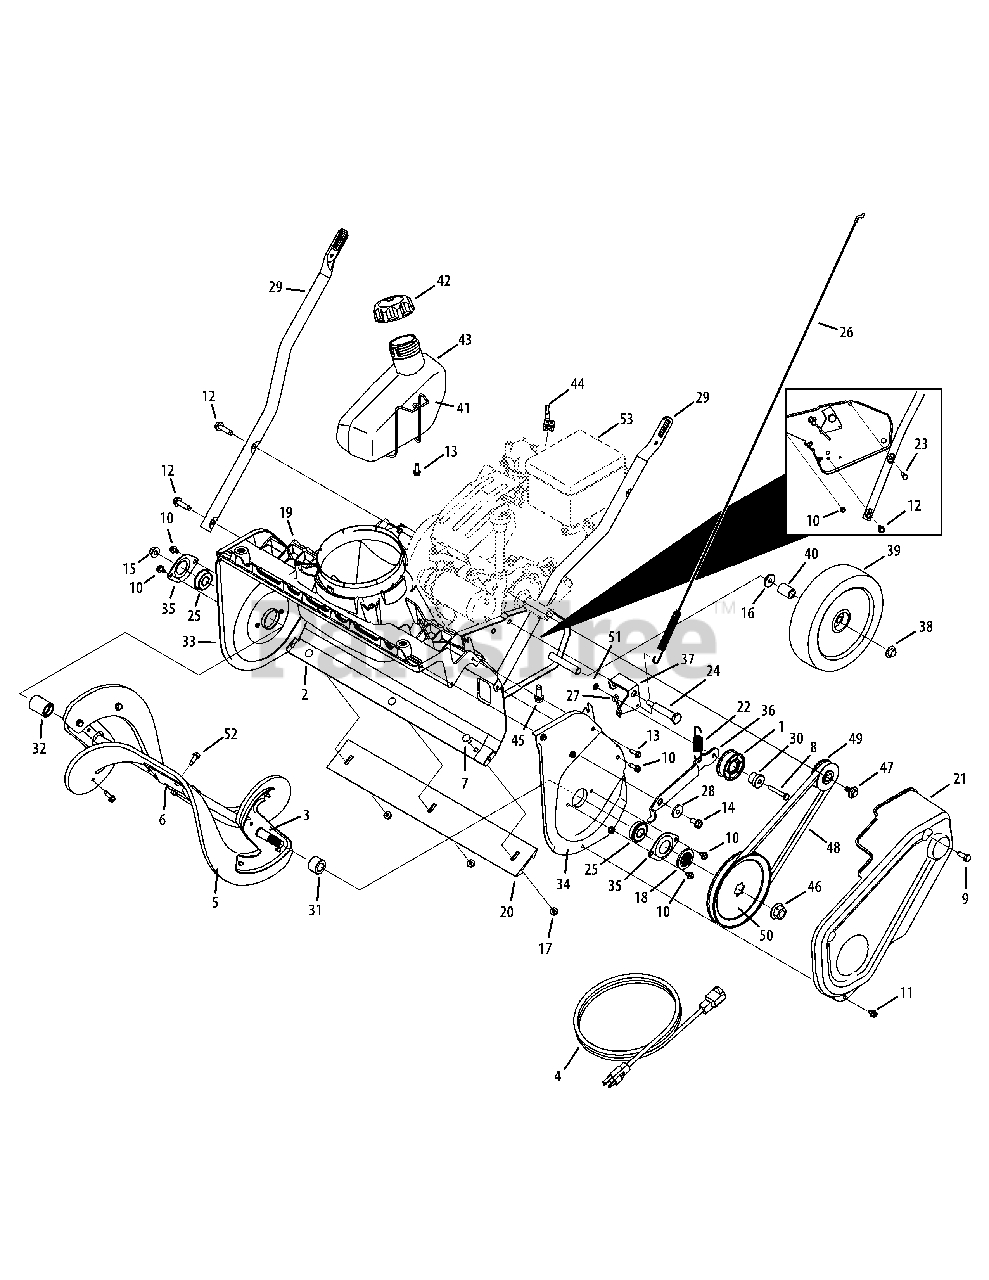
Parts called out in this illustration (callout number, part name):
1	Idler Pulley Assembly
2	Frame
3	Auger Assembly Complete
4	3-Prong Extension Cord
5	Rubber Auger Paddle Kit
6	Center Auger Bracket
6	Hex Washer Screw 1/4-20 x.750
7	Carriage Screw, 1/4-20 x .62
8	Hex Screw, 1/4-20 x 1.50
9	Hex Lock Screw, 5/16-24 x .750
10	Hex Washer Screw, 1/4-20 x .750
11	Hex Washer Screw, 1/4-20 x .500
12	Hex Washer Screw, 5/16-18 x 1.250
13	Hex Washer Screw, 1/4-15 x .750
14	Hex Washer Screw, 5/16-18 x .75
15	Flange Lock Nut, 3/8-16
16	Flat Washer, .535 x .930 x .090
17	Flange Lock Nut, 1/4-20
18	Pulley Hub
19	Chute Adapter
20	Shave Plate
22	Extension Spring, .70 x 3.035
23	Hex Screw, 5/16-24 x 1.25
24	Shoulder Bolt, 5/16-24 x .496 x 2.18
25	Ball Bearing, .500 x 40mm x 12mm
26	Clutch Cable
27	Drive Cable Wire Support
28	Shoulder Spacer
30	Shoulder Spacer, .260 x .785 x .538
31	LH Auger Spacer
32	RH Auger Spacer
33	RH Auger Plate
34	LH Auger Plate
36	Idler Bracket
38	Push Cap, 1/2
40	Sleeve Spacer, .525 x .78 x 1.00
41	Gas Tank Wire Support
42	Fuel Cap
43	Fuel Tank
44	Choke Extension Lever
45	Hex Washer Screw, 3/8-16 x 1.000
46	Flange Nut, 7/16-20
47	Hex Cap Screw, 5/16-24 x .75
48	Belt, .500 x 35.06
49	Pulley Half, .625 x 2.25
50	Pulley, 1/2 x 6.00
52	Hex Washer Screw 1/4-20 x.750
53	Replacement Engine
